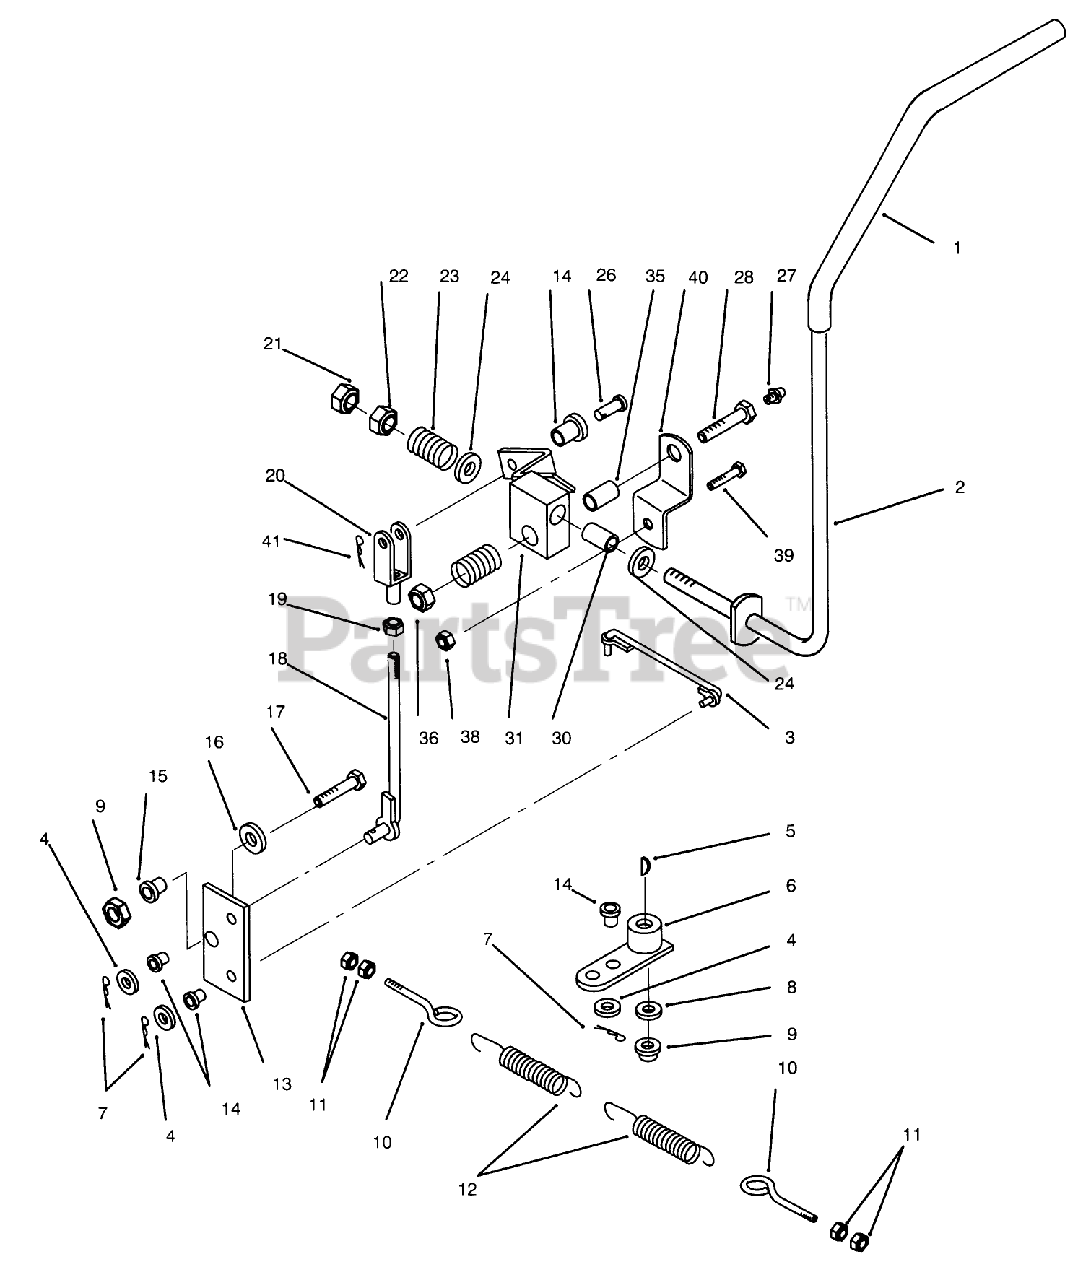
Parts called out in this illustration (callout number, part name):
1	GRIP-CUSHION
2	WLDMT-STEER LVR LH B
3	ROD-STEERING R.H.
4	WASHER-PLAIN
5	KEY WOODR 1/8X1/2 DI
6	Arm-Hydro Control
7	PIN-COTTER
8	WASHER-FLAT
9	NUT-LOCK, NI
10	EYE BOLT 1/4-20
11	NUT-HEX
12	SPG-NEUTRAL 20217-35
13	PLATE-STEERING PI B
14	BUSHING-FLANGED
15	SPACER-LIFT LINK
16	WASHER
17	SCREW-HH
18	ASS'Y-ROD
19	NUT-HEX
20	YOKE
21	NUT-JAM
22	NUT-LOCK, NI
23	SPRING
24	WASHER-FLAT
26	PIN-YOKE
27	FITTING-GREASE
28	Bolt-Shoulder (Incl. Ref. #27)
30	BUSHING-STR LVR PVT
31	Steering Lever LH
35	BUSHING
36	NUT-LOCK, NI
38	NUT-LOCK, NI
39	SCREW-HH
40	STRAP-PIVOT B
41	PIN-HAIR
